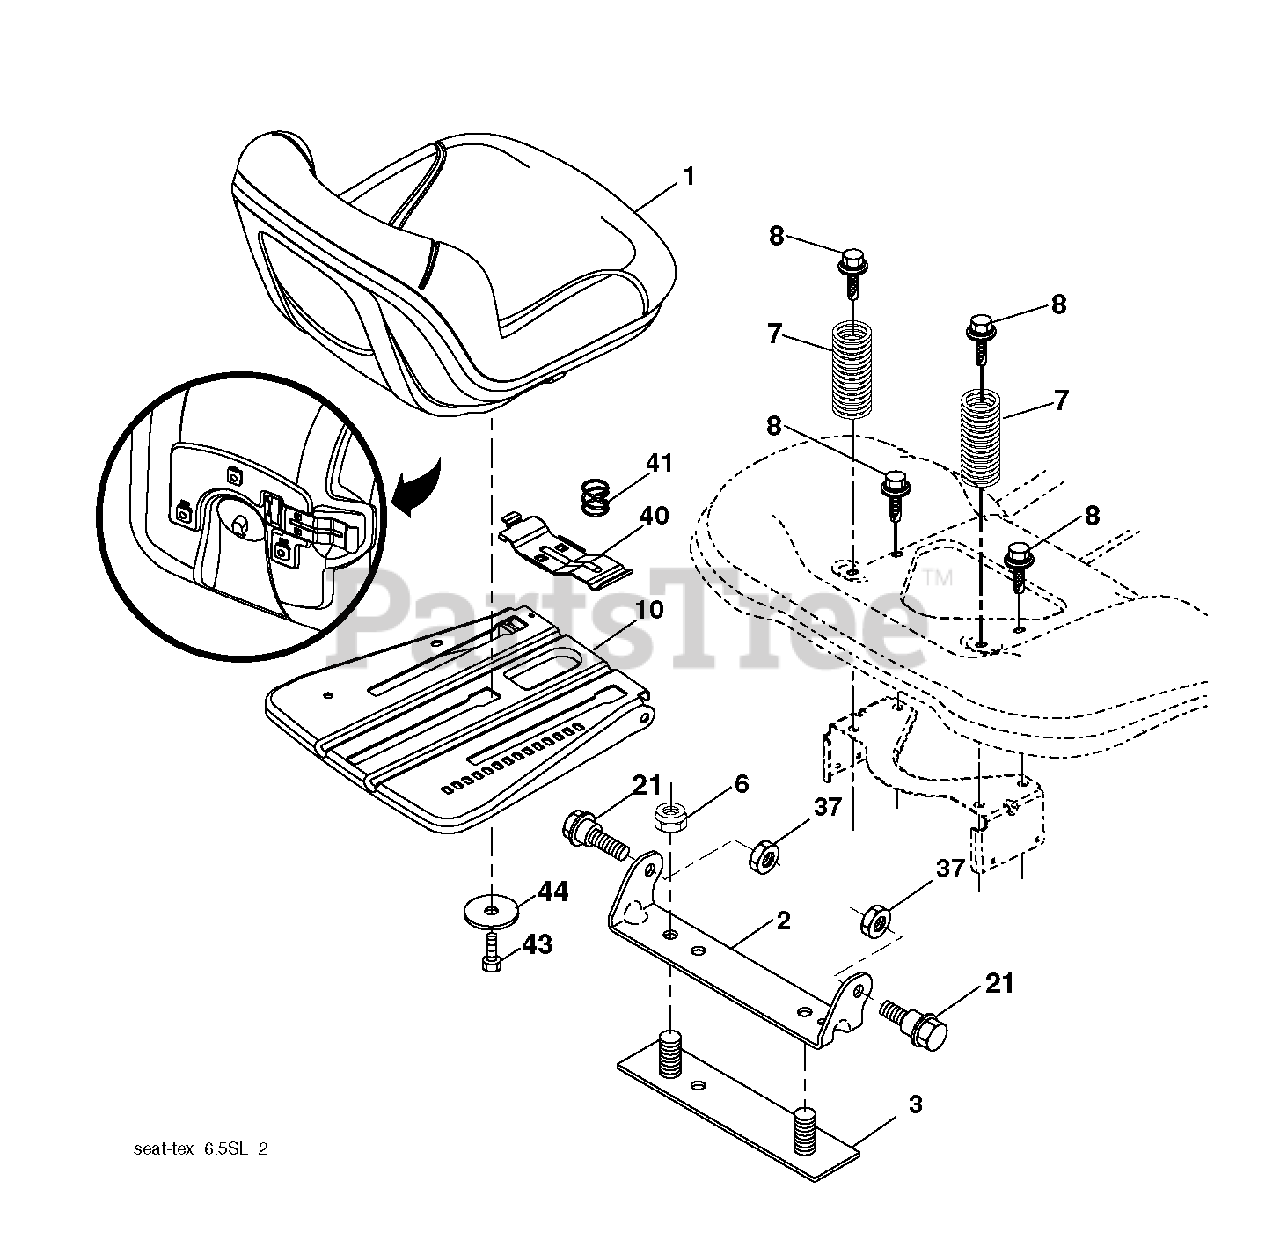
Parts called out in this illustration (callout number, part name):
2	BRKT.PIVOT.FENDER
3	STRAP
8	BOLT, 5/16-18 X 1 3/4
10	PAN.ASM.SEAT.3PT
21	BOLT, SHOULDER
40	HANDLE.SLIDE.SEAT.TEX.
41	SPRING.LATCH.SEAT.TEX
44	WASHER 13/32 X 2-3/8 X 12GA
